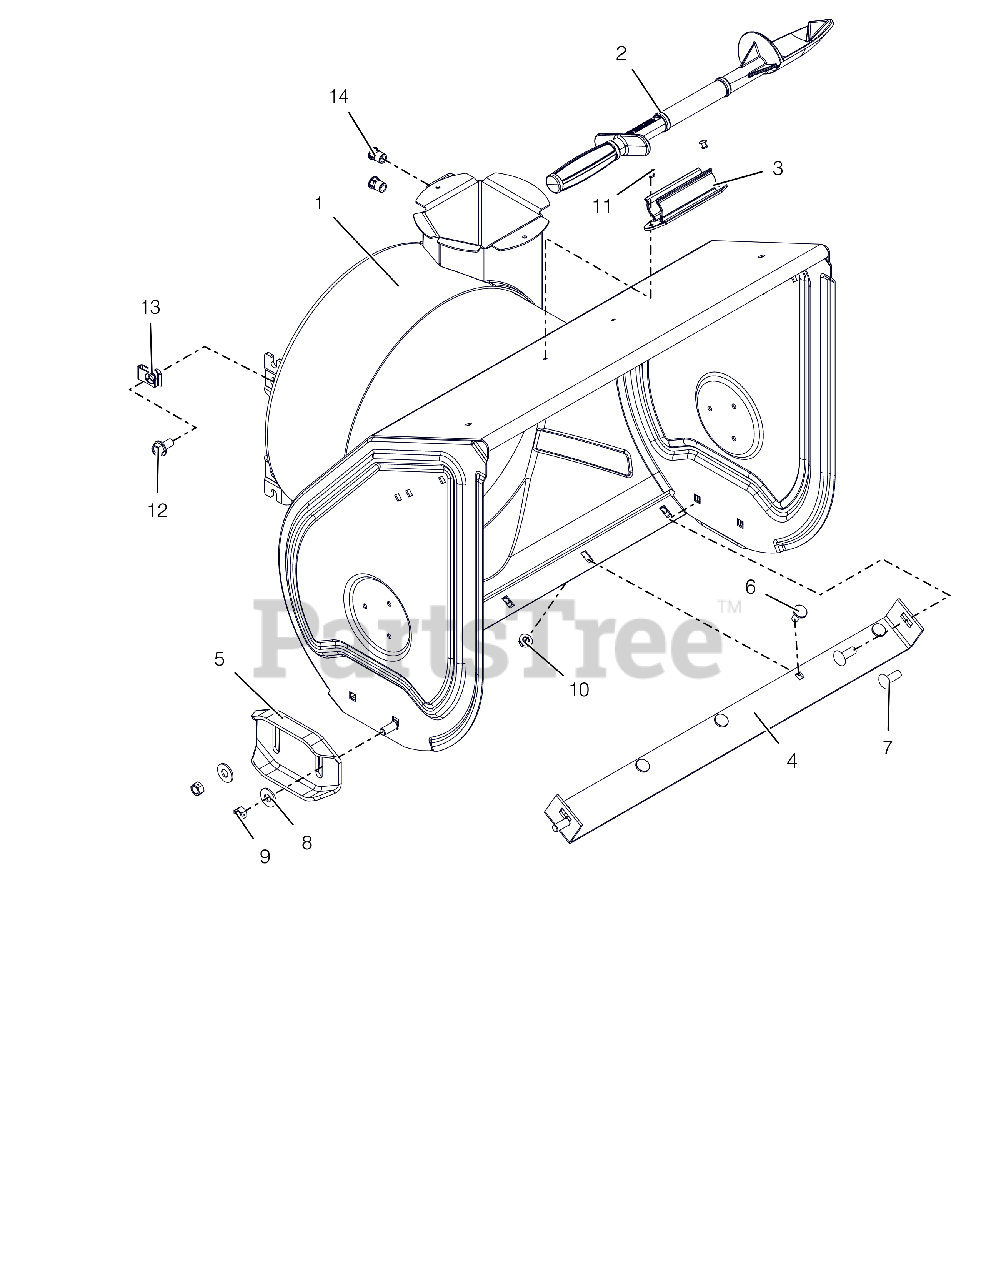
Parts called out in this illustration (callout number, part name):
1	BLOWER HOUSING W/DECAL 24"
2	DEVICE, SNOW CLEAN OUT
3	MOUNT, SNOW CLEAN OUT
4	BLADE, SCRAPER-24"
5	SKID SHOE, REVERSIBLE - ORANGE
6	BOLT, MODIFIED HEAD CARRIAGE
7	@BLT-RDHDSHSQNK.38-16X1.0 G5YZ
8	@WSHR-FL-STL.438X1.00X.083 YWZ
9	@NUT-LK-CTR .38-16 YWZC
10	@NUT-LK-TOP-FLG .31-18 YWZC
11	RVT-POP .187 YZ
12	BLT-SERHFWH .38-16X.75 YWZC
13	NUT-RTNR .375-16X.37
14	NUT, THREADED INSERT .38-16
